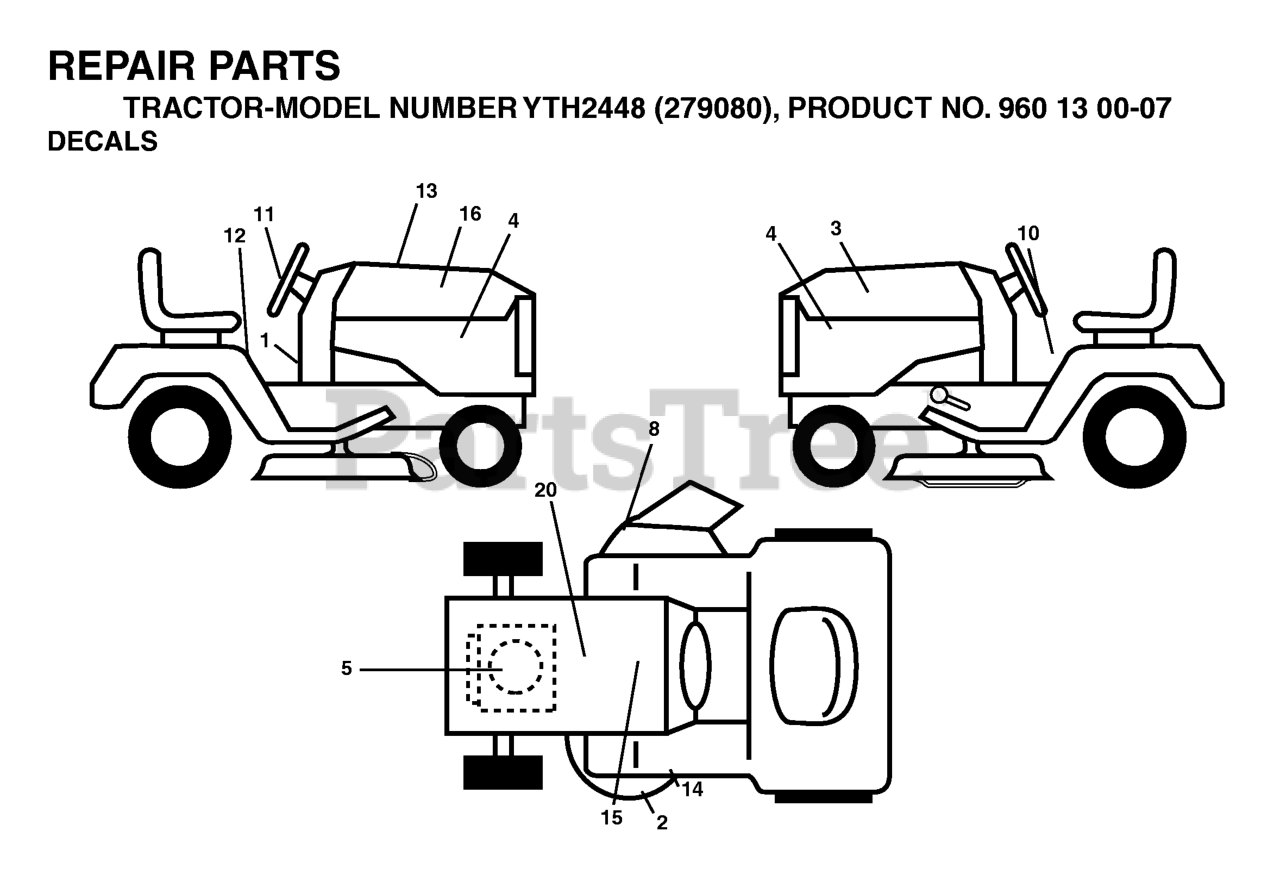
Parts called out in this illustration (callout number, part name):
4	DECAL, PANEL YTH2448
5	DECAL.ENG.BS.24HP
8	DECAL.WARN.KEEP.HAND.AWAY
10	DECAL FENDER DANGER
11	DECAL.STEERING.HUSQ.BLUE
13	DECAL HOOD CUST. RESP.
14	DECAL V-BELT SCHEMATIC
15	DECAL. HD. RPL. HUSQ
20	DECAL BTRY SYMBOLS
